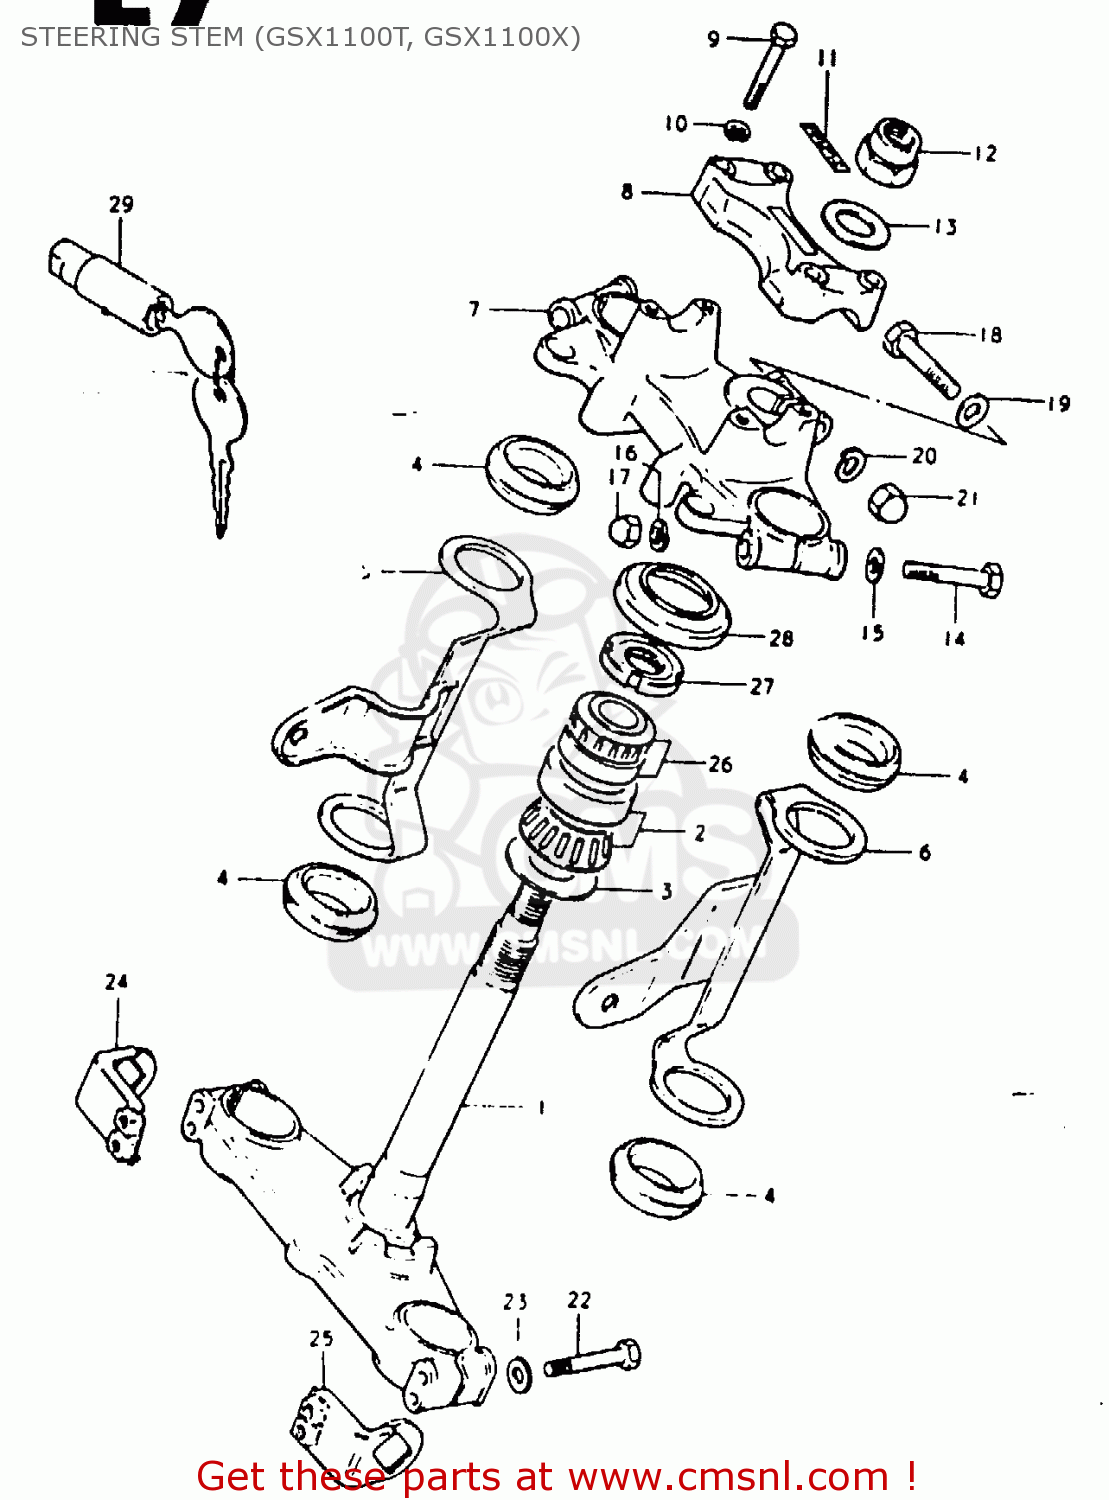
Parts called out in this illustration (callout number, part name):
1	STEM,STEERING
2	BEARING
3	WASHER,THRUST
4	CUSHION,HEADLAMP BRACKET
5	BRACKET, HEADLAMP RH
6	BRACKET, HEADLAMP LH
7	HEAD,STEERING STEM
8	HOLDER, HANDLE
9	BOLT
10	LOCK WASHER
11	EMBLEM,HANDLE CLAMP
12	NUT,FR FORK UPR BRACKET
13	WASHER
14	BOLT
15	WASHER
16	LOCK WASHER
17	NUT 10MM
18	BOLT 8X50
19	WASHER
20	WASHER,LOCK,8.
21	NUT,M8X1.25X12
22	BOLT 8X55
23	WASHER
24	BRACKET, TURN SIGNAL RH
25	BRACKET, TURN SIGNAL LH
26	TAPER,ROLLER BEARING
27	NUT,STEERING STEM(25X44X10)
28	DUST SEAL,STEERING,UPPER
